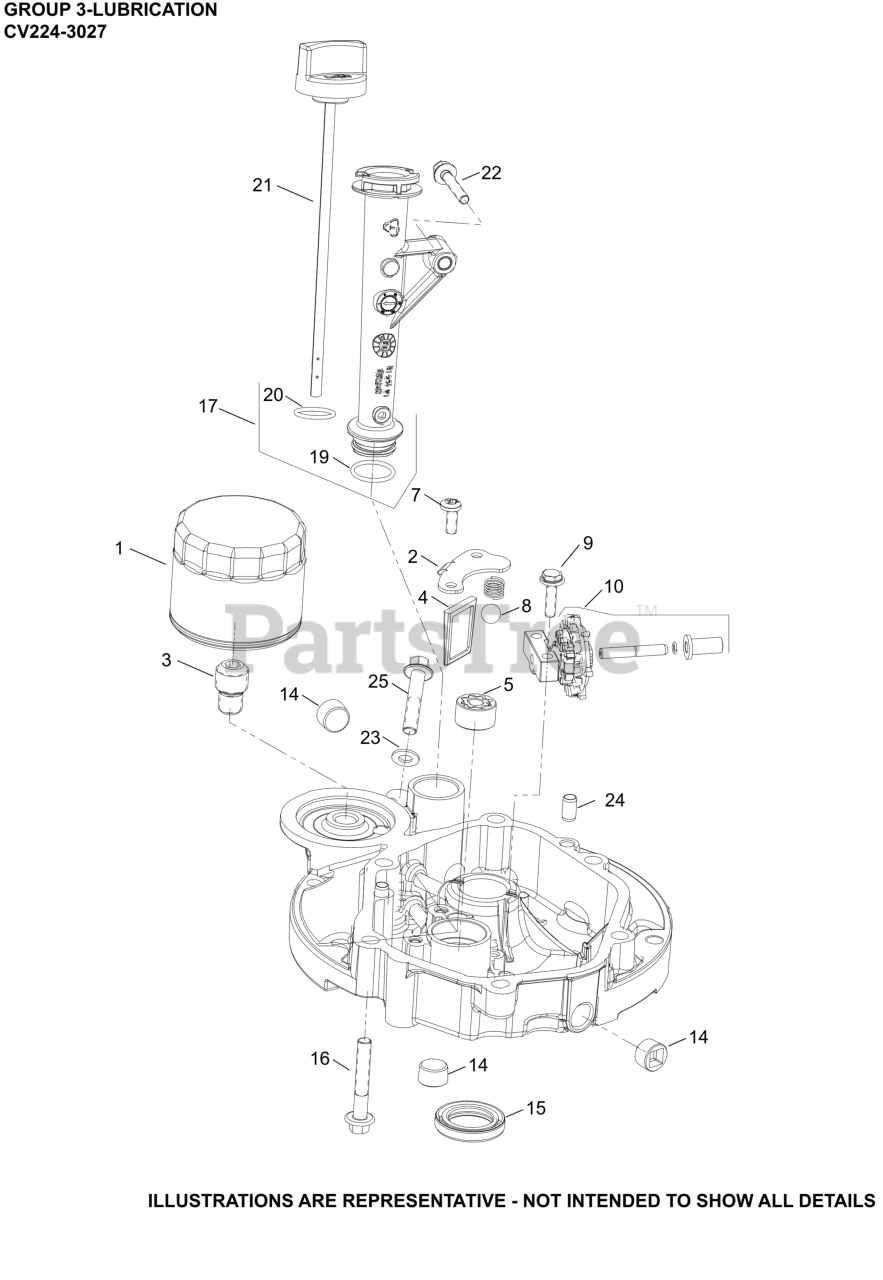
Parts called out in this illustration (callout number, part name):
1	FILTER, OIL
2	COVER, OIL PUMP SCREEN
3	NIPPLE, OIL FILTER
4	SCREEN, OIL
5	PUMP ASSEMBLY, OIL (GE-ROTOR)
7	SCREW, M6 X 16
8	BALL, STEEL COMPOSITE
9	SCREW, M6 X 22
10	GOVERNOR GEAR, ASSEMBLY
14	PLUG, PIPE (W/SEALANT)
16	SCREW, HEX FLANGE (M8)-USE 25 086 456-S
17	TUBE ASSEMBLY OIL FILL
19	O-RING, OIL FILL TUBE
20	O-RING (CAP)
22	SCREW, HEX FLANGE (M6)-(#25086435S)
23	WASHER, CLEAN OIL SCREW
24	PIN, DOWEL (8mm)
25	SCREW, CLOSURE PLATE
